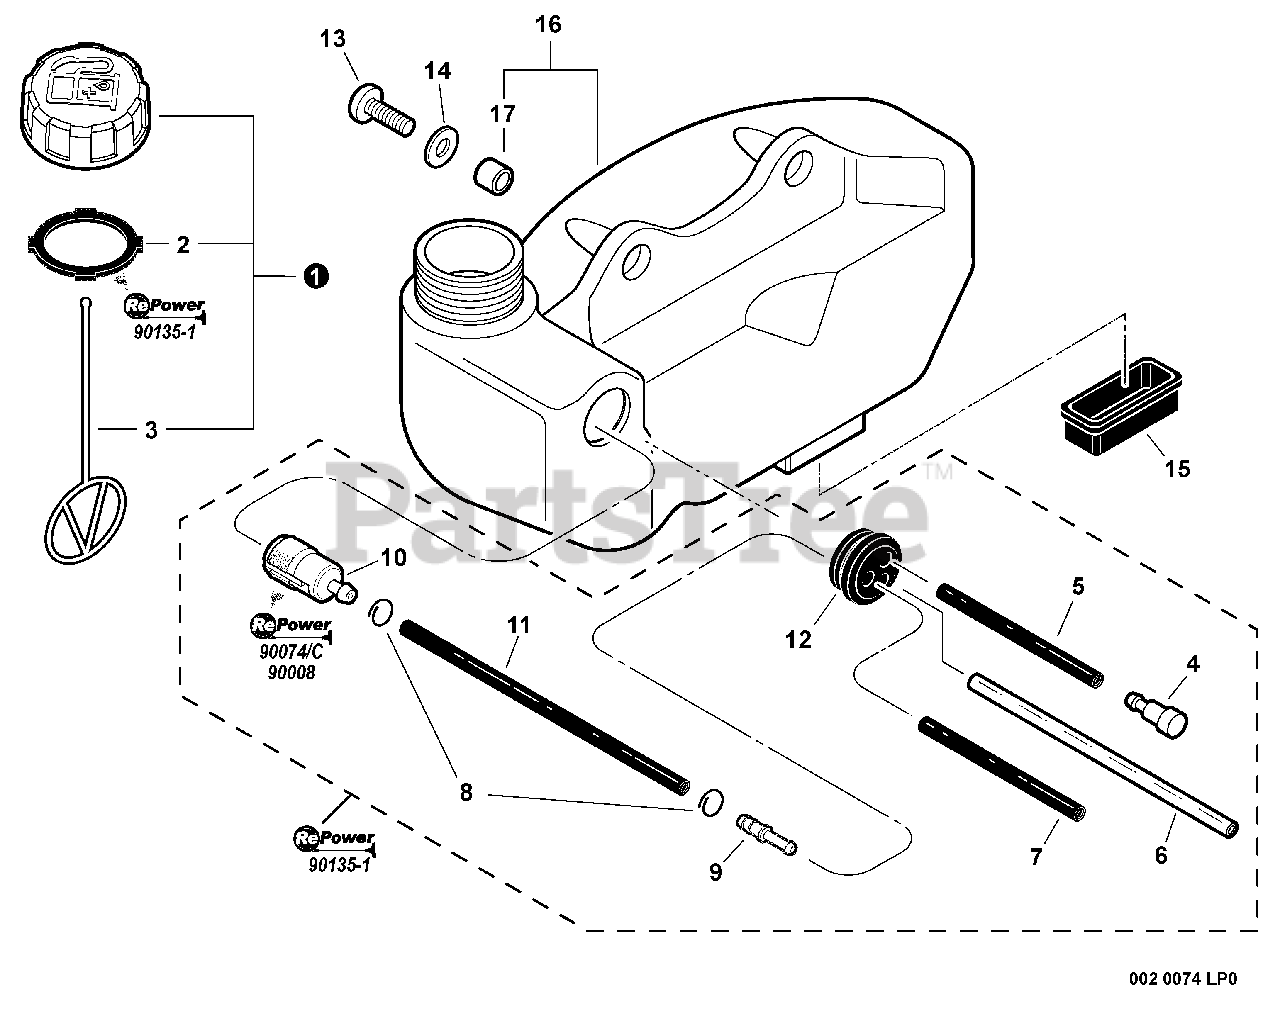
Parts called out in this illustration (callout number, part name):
1	CAP ASSY - ORANGE
2	GASKET, CAP
3	CONNECTOR, CAP
4	VENT, FUEL TANK
5	PIPE - 3X5X70 -- BLACK
6	PIPE - 3X6X110 -- CLEAR
7	PIPE - 3X5X87 -- BLACK
8	CLIP - 6
9	CONNECTOR, PIPE
10	FILTER, FUEL
11	PIPE - 3X5X115 -- BLACK
13	SCREW - 5X16 -- TAPPING
14	WASHER - 5
15	CUSHION, FUEL TANK
16	FUEL TANK ASSY
18	RePower FUEL SYSTEM KIT
19	RePower TUNE-UP KIT
20	RePower FILTER KIT
